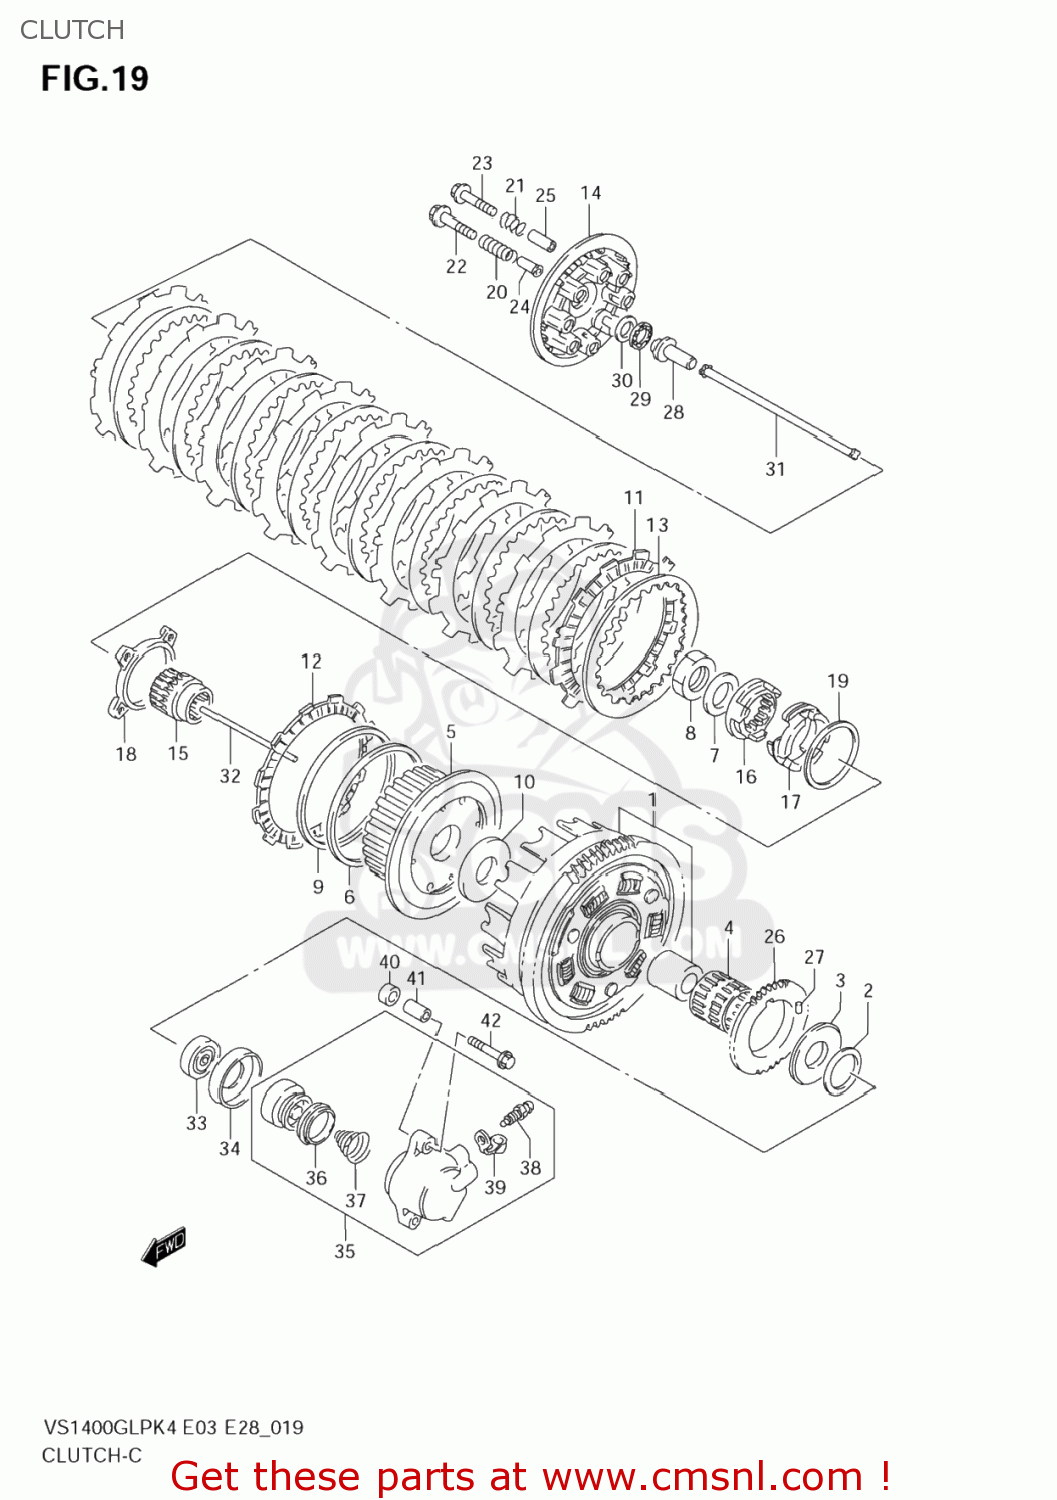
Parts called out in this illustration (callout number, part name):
1	GEAR ASSY,PRI DRIVEN
2	WASHER(25X38X2.5)
3	WASHER(25X54X2.5)
4	BEARING(35X40X35.8)
5	HUB,CLUTCH SLEEVE
6	SEAT,WAVE WASHER(T:1.4)
7	WASHER
8	NUT
9	WASHER
10	WASHER(25X60X2.5)
11	PLATE,CLUTCH DRIVE (NAS)
12	PLATE,CLUTCH DRIVE(T:3.5) (NAS)
13	PLATE,CLUTCH DRIVEN (NAS)
14	DISC,CLUTCH PRESSURE
15	SPACER,CLUTCH SLEEVE HUB
16	CAM,CLUTCH NO.1
17	CAM,CLUTCH NO.2
18	SLIDER,CLUTCH SPRING
19	WASHER(54X62X1)
20	SPRING
21	SPRING
22	BOLT(6X40)
23	BOLT(6X35)
24	SPACER(6.4X10X22)
25	SPACER(6.5X9X24.1)
26	GEAR,OIL PUMP DRIVE
27	PIN(6X6)
28	PIECE,CLUTCH PUSH
29	BEARING(15X28X2)
30	WASHER(15.5X28X1)
31	ROD,CLUTCH PUSH,R
32	ROD,CLUTCH PUSH,L
33	SEAL,OIL(6X34X10.5)
34	RETAINER,CL PUSH ROD OIL SEAL
35	CYLINDER,CLUTCH RELEASE
36	CUP
37	SPRING,CLUTCH CYLINDER
38	BLEEDER
39	CAP,BLEEDER
40	SPACER(9X16X11)
41	PIN(6.4X9X23)
42	BOLT
